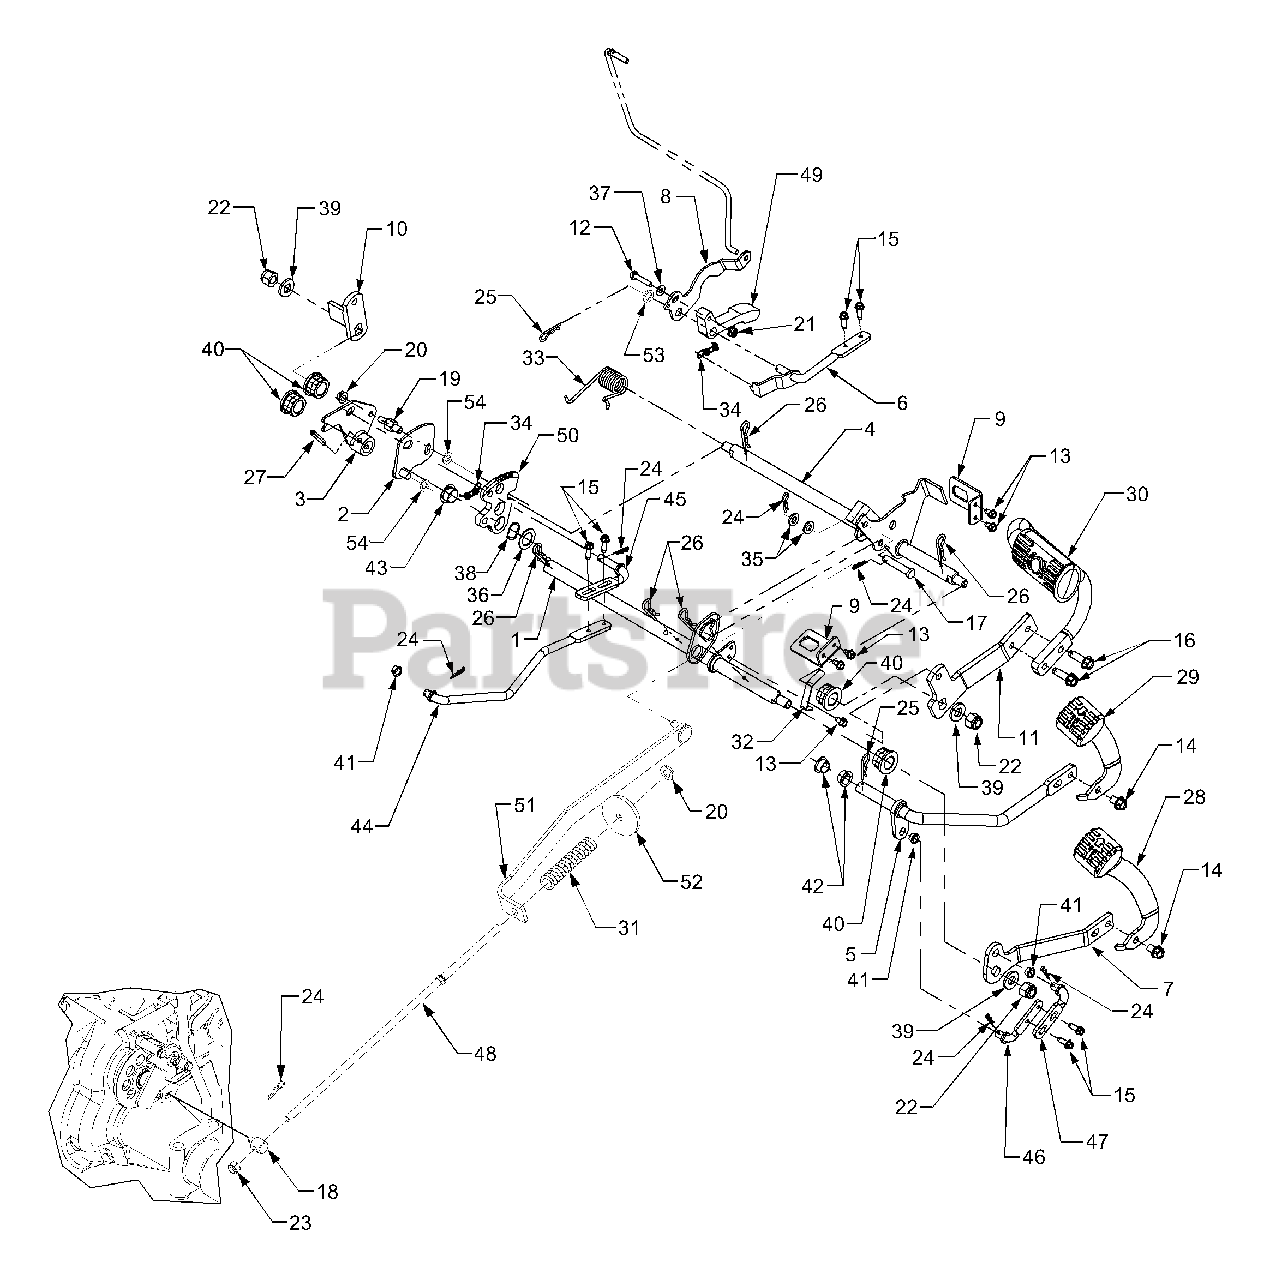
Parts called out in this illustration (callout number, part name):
1	Shaft Assembly, Pedal
2	Plate, Disengagement
4	Shaft Assembly, Brake
5	Shaft Assembly, Reverse
6	Rod Assembly, Cruise
7	Link, Pedal Mounting
8	Bracket, Rod Adjust
9	Bracket, Switch
10	Lever, Brake Diff Lock
11	Link, Brake Pedal
12	Screw, Hex Cap, 1/4-20 x 1.25 GR5
13	Screw, Hex Wash. Hd. Tapp 1/4-20 x .5
14	Screw, Hex Wash. Hd. Tapp 3/8-16 x .75
15	Screw, Hex Wash. Hd. Tapp 1/4-20 x .75
16	Screw, Hex Wash. Hd. Tapp 3/8-16 x 1.25
17	Pin, Clevis, 3/8 x 2.015
18	Ferrule, Adjust.
19	Stud, Actuator
20	Nut, Hex Flange Lock, 5/16-18
21	Nut, Hex Flange Lock, 1/4-20
22	Nut, Hex Insert Lock, 1/2-20
23	Nut, Hex Insert Lock, 5/16-18
24	Pin, Internal Cotter
25	Pin, Internal Cotter
26	Pin, Internal Cotter
27	Pin, Spiral Spring, .25 x 1.5
28	Pedal, Forward
29	Pedal, Reverse
30	Pedal, Brake
31	Spring, Compression
32	Spring, No Cut Reverse
33	Spring, Torsion
34	Spring, Extension, .380 OD x 1.44
35	Washer, Flat, .344 x .688 x .065
36	Washer, Flat, .79 x 1.24 x .060
37	Washer, Flat, .25 x .62
38	Washer, Wave, .785 x 1.0 x .012
39	Washer, Flat, .531 x 1.06 x .134
40	Bearing, Hex Flange
41	Bearing, Flange
42	Bearing, Flange
43	Bearing, Flange
44	Rod, Rear Control
45	Rod, Front Control
46	Rod, Rear Connecting
47	Rod, Front Connecting
48	Rod, Brake
49	Cruise Latch
50	Plate, Cruise
51	Link Assembly, Brake
52	Washer, Flat, .341 x 2.25 x .10
53	Washer, Flat, .53 x .93 x .050
54	Washer, Flat, .385 x .870 x .092
